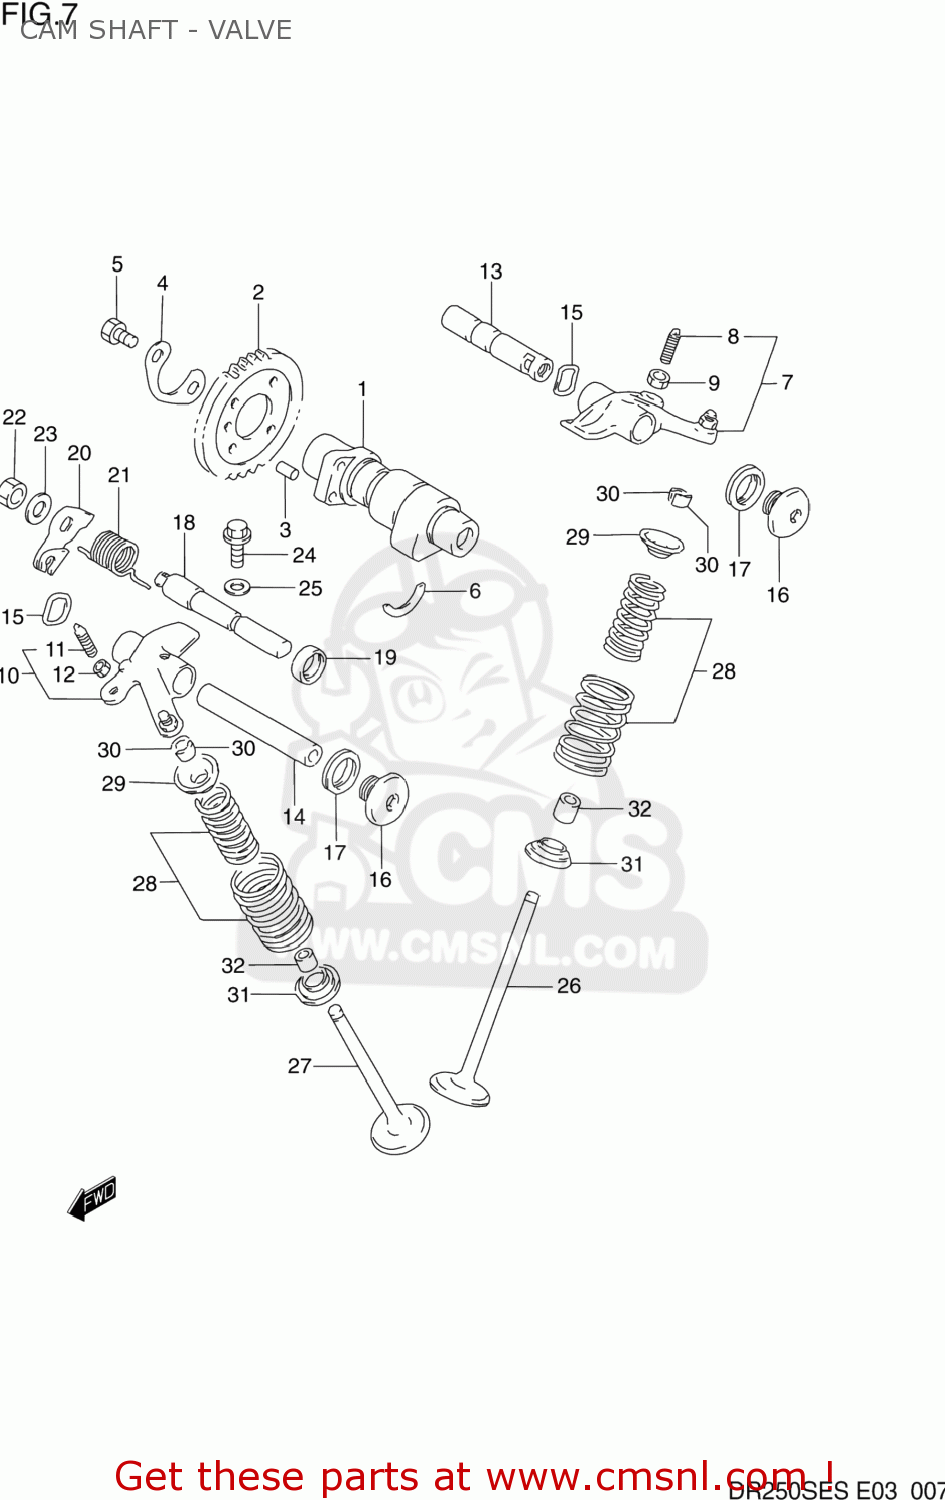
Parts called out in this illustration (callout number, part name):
1	CAMSHAFT
2	SPROCKET,CAMSHAFT INTAKE
3	PIN(5X8)
4	WASHER,SPROCKET
5	BOLT(6X10.5)
6	C RING
7	ARM,VALVE ROCKER INTAKE
8	SCREW,TAPPET ADJUSTING
9	NUT,ADJUSTING
10	ARM,VALVE ROCKER EXHAUST
11	SCREW,TAPPET ADJUSTING
12	NUT,ADJUSTING
13	SHAFT,VALVE ROCKER ARM INTAKE
14	SHAFT,VALVE ROCKER ARM EXHAUST
15	WASHER
16	PLUG,14X12
17	GASKET(14X19.2X2) (NAS)
18	SHAFT,DECOMP
19	SEAL,OIL(10X17X6)
20	LEVER,DECOMPRESSION SHAFT
21	SPRING
22	NUT 8MM
23	WASHER
24	BOLT
25	GASKET(6.4X11.5X0.8) (NAS)
26	VALVE,INTAKE
27	VALVE,EXHAUST
28	SPRING SET,VALVE
29	RETAINER,VALVE SPRING
30	COTTER VALVE
31	SEAT,VALVE SPRING
32	SEAL,OIL(5X10X9.7)
